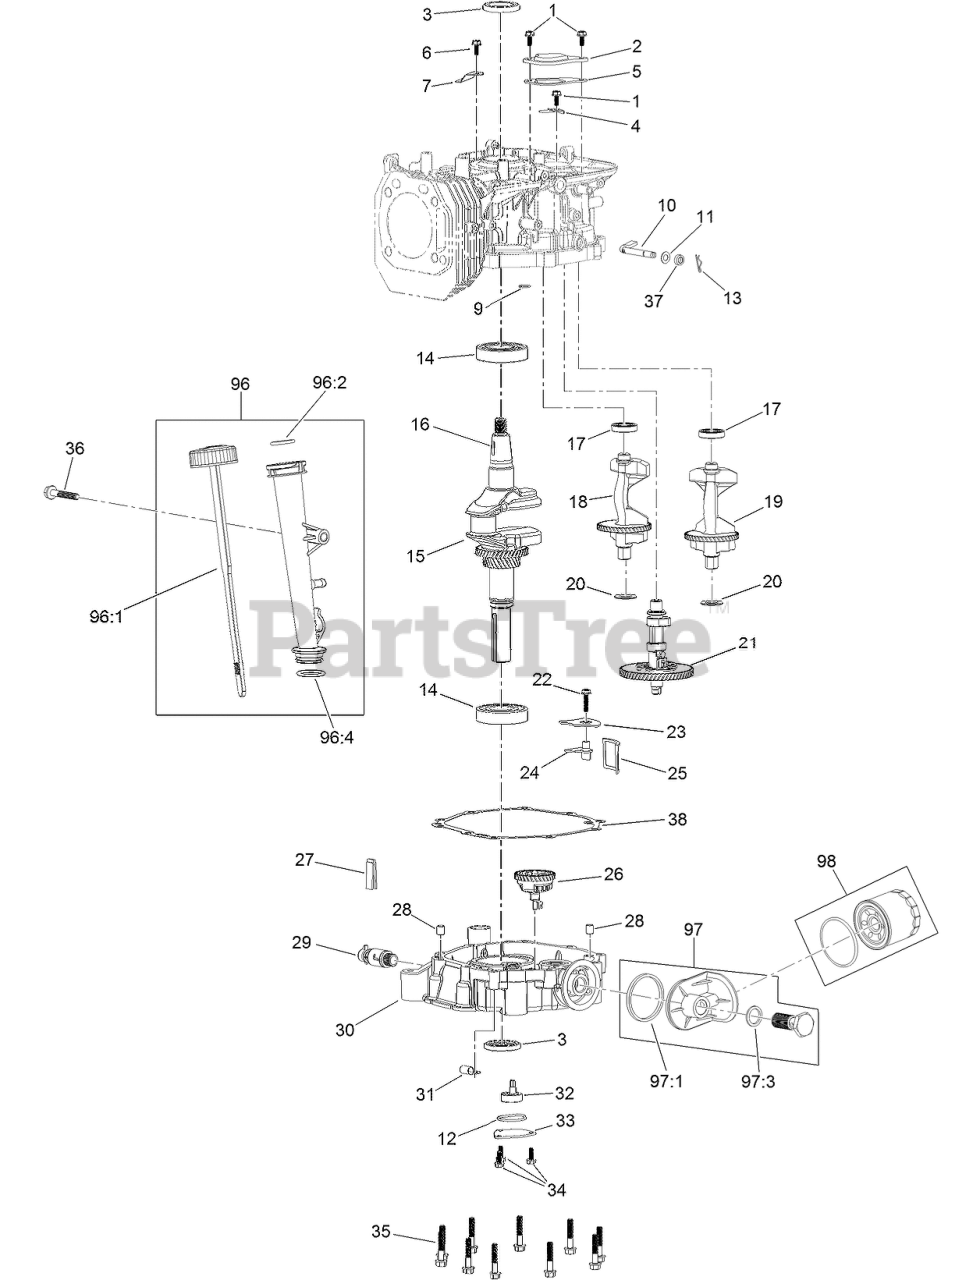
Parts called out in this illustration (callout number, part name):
1	SCREW-HHF
2	PLATE-BREATHER
3	SEAL-OIL
4	VALVE-REED
5	GASKET-BREATHER
6	SCREW-HHF
7	RETAINER
9	O-RING
10	SHAFT-GOVERNOR
11	WASHER-PLAIN
12	SEAL-PUMP, OIL
13	PIN-HAIR
14	BEARING-BALL
15	CRANKSHAFT
16	KEY-WOODRUFF
17	BEARING-BALL
18	SHAFT-BALANCE, R
19	SHAFT-BALANCE, L
20	WASHER
21	CAMSHAFT
22	SCREW-HHF
23	COVER-STRAINER, OIL
24	PLATE-BAFFLE, OIL
25	STRAINER-OIL
26	GEAR-GOVERNOR
27	DEFLECTOR-OIL, RUBBER
28	PIN-DOWEL
29	VALVE-DRAIN, OIL
30	COVER-CRANKCASE
31	CLAMP-HOSE
32	OIL PUMP ASM
33	COVER-PUMP, OIL
34	SCREW-HHF
35	SCREW-HHF
36	SCREW-HHF
37	SEAL-OIL
38	GASKET-CRANKCASE
96	DIPSTICK AND TUBE KIT
96:1	DIPSTICK ASM
96:2	O-RING
96:4	O-RING
97	OIL ADAPTOR KIT
97:1	SEAL-ADAPTOR, OIL
97:3	WASHER-FILTER, OIL
98	FILTER-OIL
